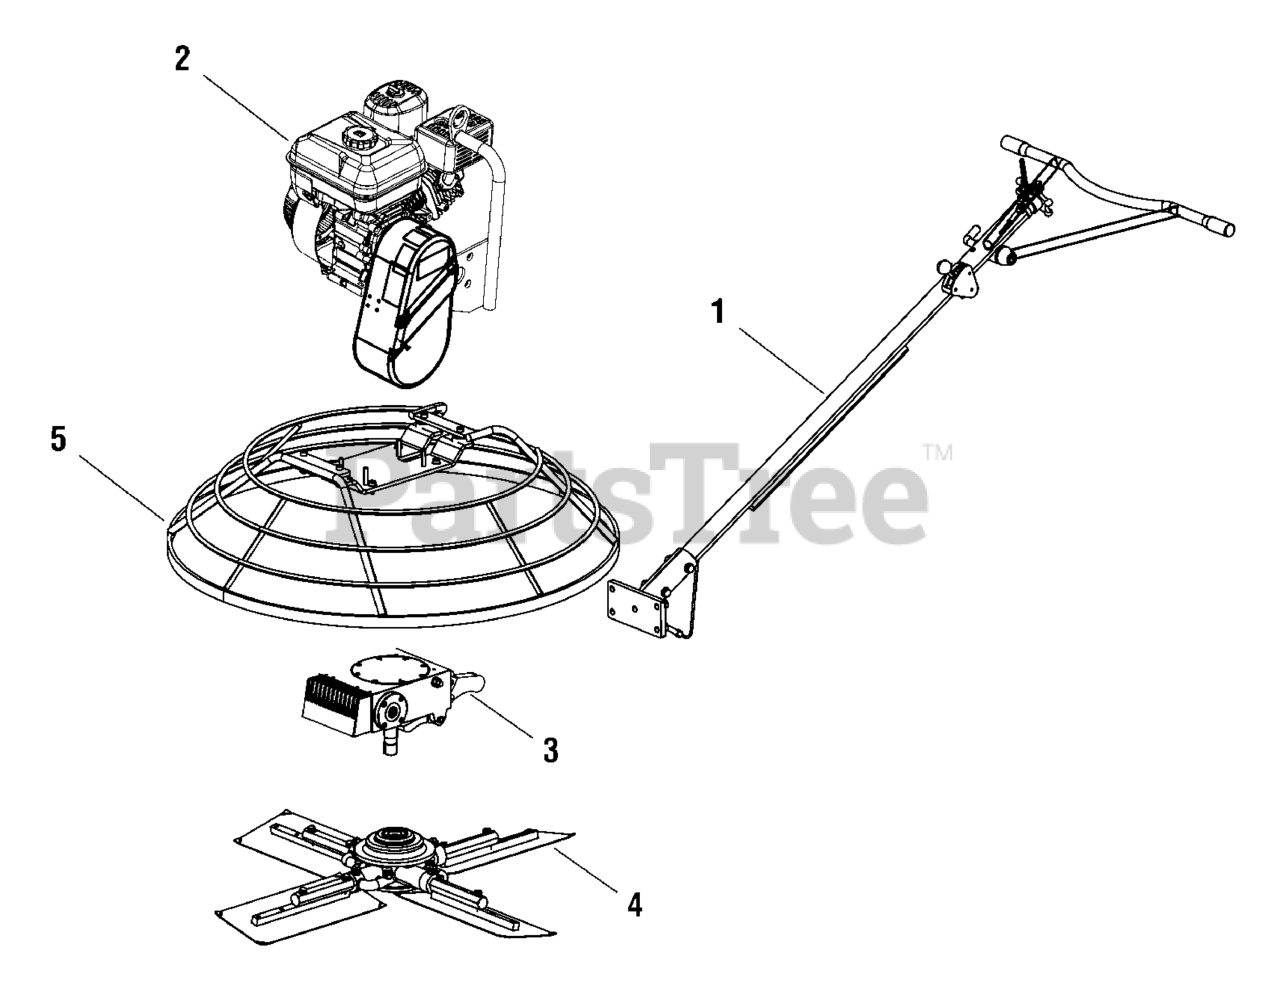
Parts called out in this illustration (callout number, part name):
1	HANDLE ASSEMBLY
2	ENGINE ASSEMBLY
3	REDUCTION GEAR BOX
4	CROSS BLADE ASSEMBLY
5	BLADE ASSEMBLY
